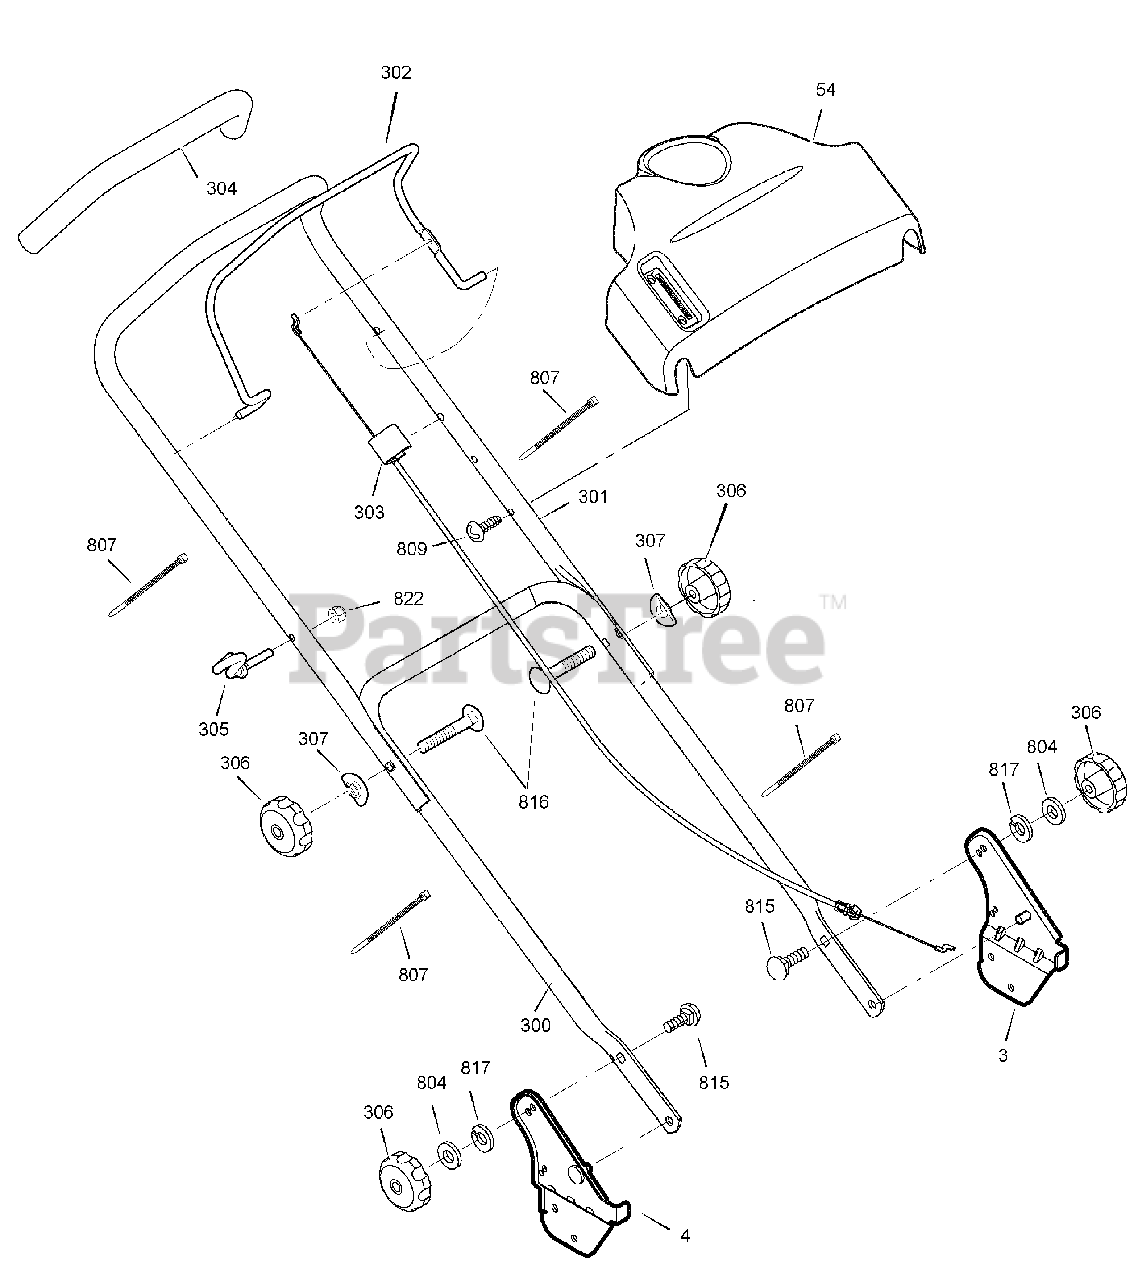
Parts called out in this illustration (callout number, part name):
3	BRACKET ASSEMBLY, Left Handle
4	BRACKET ASSEMBLY, Right Handle
54	CONTROL PANEL
300	HANDLE, Lower
301	HANDLE, Upper
302	LEVER, Engine Stop
303	CABLE, Engine Stop
304	TUBING, Foam
305	GUIDE, Rope
306	KNOB, Adjuster
307	WASHER, Formed
804	WASHER, 5/8
807	CABLE TIE
809	SCREW, Self Tap, #10-16 x 1/2
815	BOLT, Carriage, 5/16-18 x 1-1/8
816	BOLT, Carriage, 5/16-18 x 2
817	WASHER, Lock
822	NUT, Hex, 1/4-20
